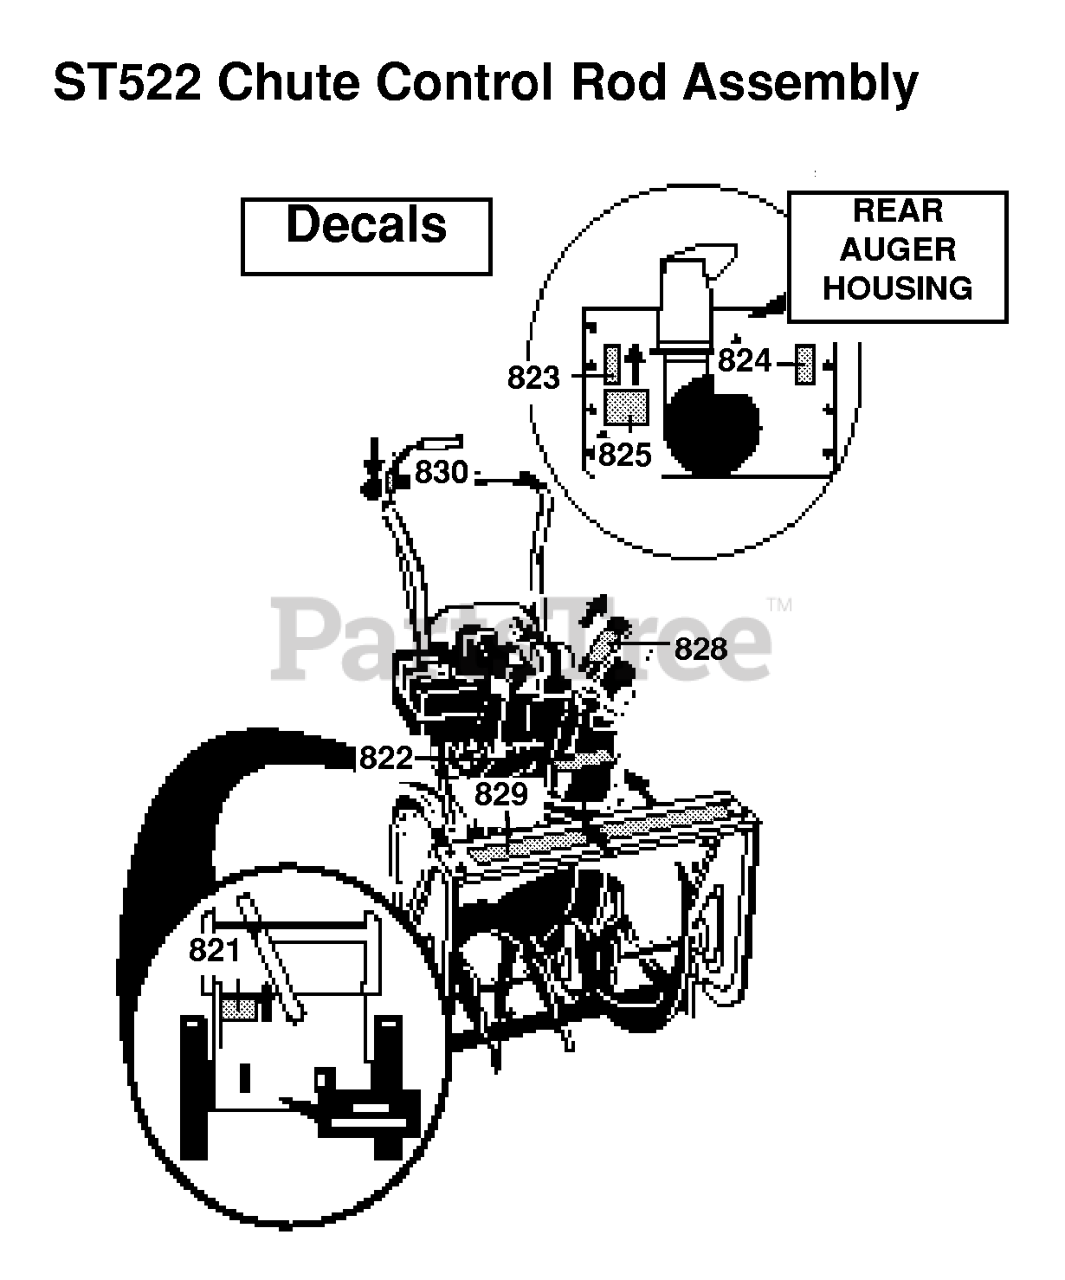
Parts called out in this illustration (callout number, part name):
822	Decal, 9" Impeller
823	DECAL, DANGER CHUTE
824	DECAL-DANGER AUGER/FOOT
825	Decal, Danger English
828	DECAL, "CROWN" UPPRE CHT
829	Decal ST522H Top Cover
830	SCREW, 1/4-20X .75 HHC
